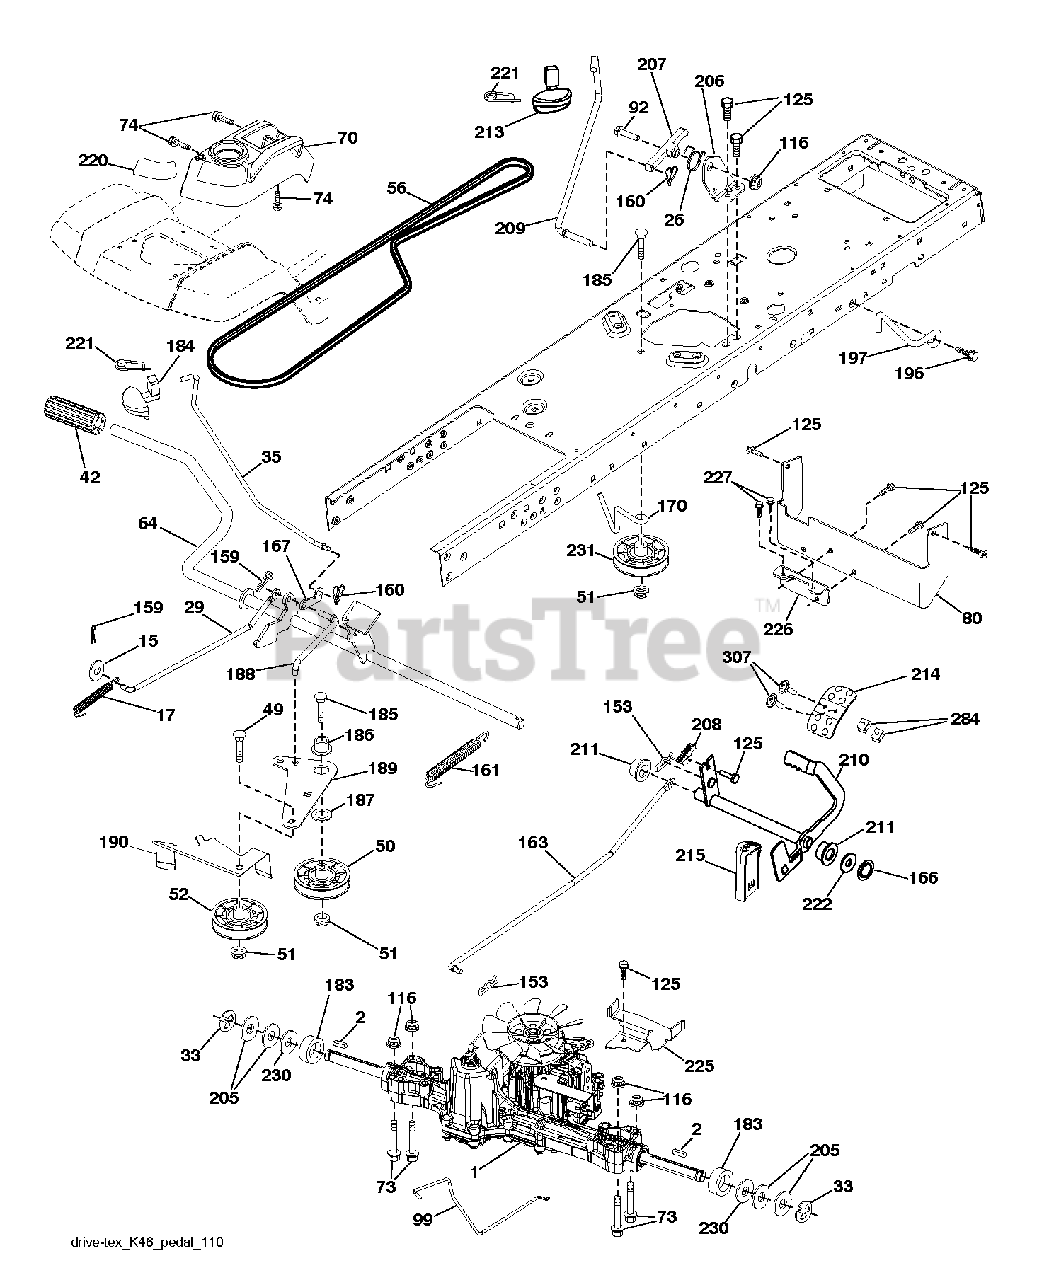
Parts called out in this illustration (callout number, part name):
1	RP TRANSAXLE (K46CR) ETC.PDL
2	SQUARE KEY
15	WASHER
17	SPRING.BRAKE.K46.GREEN
26	SPRING.RETURN.CRUISE
29	ROD.BRAKE.K46
35	ROD .BRAKE. PARKING. GT. HUSQ.
42	PEDAL COVER T
50	IDLER.FLAT.910.OFFSET
51	NUT LOCK FLG 3/8-16 UNC
52	IDLER.V-GROOVE.910.OFFSET
56	V-BELT.MOWER.92.40.42/K46
64	SHAFT.ASM.PEDAL.BRK.CNTR
70	CONSOLE.ASM.RH.GT.FC.HUSQ
73	BOLT HEX 5/16-18 GR 5
74	SCREW.HI-LO.CONSOLE
80	STRAP.TORQUE.K46.K57R.TT
92	BOLT
99	ROD.SPRING.BYPASS.K46.LT.Z
116	NUT LOCK HEX FLANGE 5/16-18
125	SCREW
153	RETAINER M
159	COTTER PIN
160	RETAINER CLIP
161	SPRING, RETURN LT
163	ROD.CONTROL.K57R.K46
166	NUT.PUSH.625
167	LATCH.BRAKE.SPRING
170	KEEPER.CENTER SPAN.1.688
183	SPACER AXLE
184	RB HANDLE.PARKG.BRK.HUS/PRED
186	SPACER.RETAINER
187	WASHER 12/32X2X10GA
188	RP LINK.CLUTCH.GROUND.DRIVE
189	BELLCRANK.GROUND.DRIVE.TEX.
190	KEEPER.BELLCRANK.DRIVE
196	SCREW 3/8-16X1
197	LINK.CLUTCH.ANIT-ROTAT
206	BRKT.MOUNT.LATCH.CRUIS
207	LATCH.CONTROL.CRUISE
208	GEAR.SECTOR.CONTROL.CR
209	ROD.CONTROL.CRUISE.GT.
210	ROCKER.ASM.PEDAL.CONTR
211	BEARING.NYLON
213	KNOB.CONTROL.CRUSIE.HU
214	PEDAL.FORWARD.HUSQVARNA.DEALER
215	PEDAL.REVERSE.TEX.GT.4
220	REFLECTOR.RH.TEX GT
221	RETAINER.SPRING.CLIP.H
222	WASHER 21/32 X 1-1/4 X 10 GA.
225	KEEPER.BELT.TRANSAXLE.K46
226	BRACKET.MOUNT.TORQUE.K46.TLT
227	SCREW
230	WASHER.HARDENED
231	IDLER.V-GROOVE.1.688.OFFSET
284	NUT.U-CHNL.1/4-20.550DP.350PNL
307	SCREW.MACHINE.CR.1/4-20
